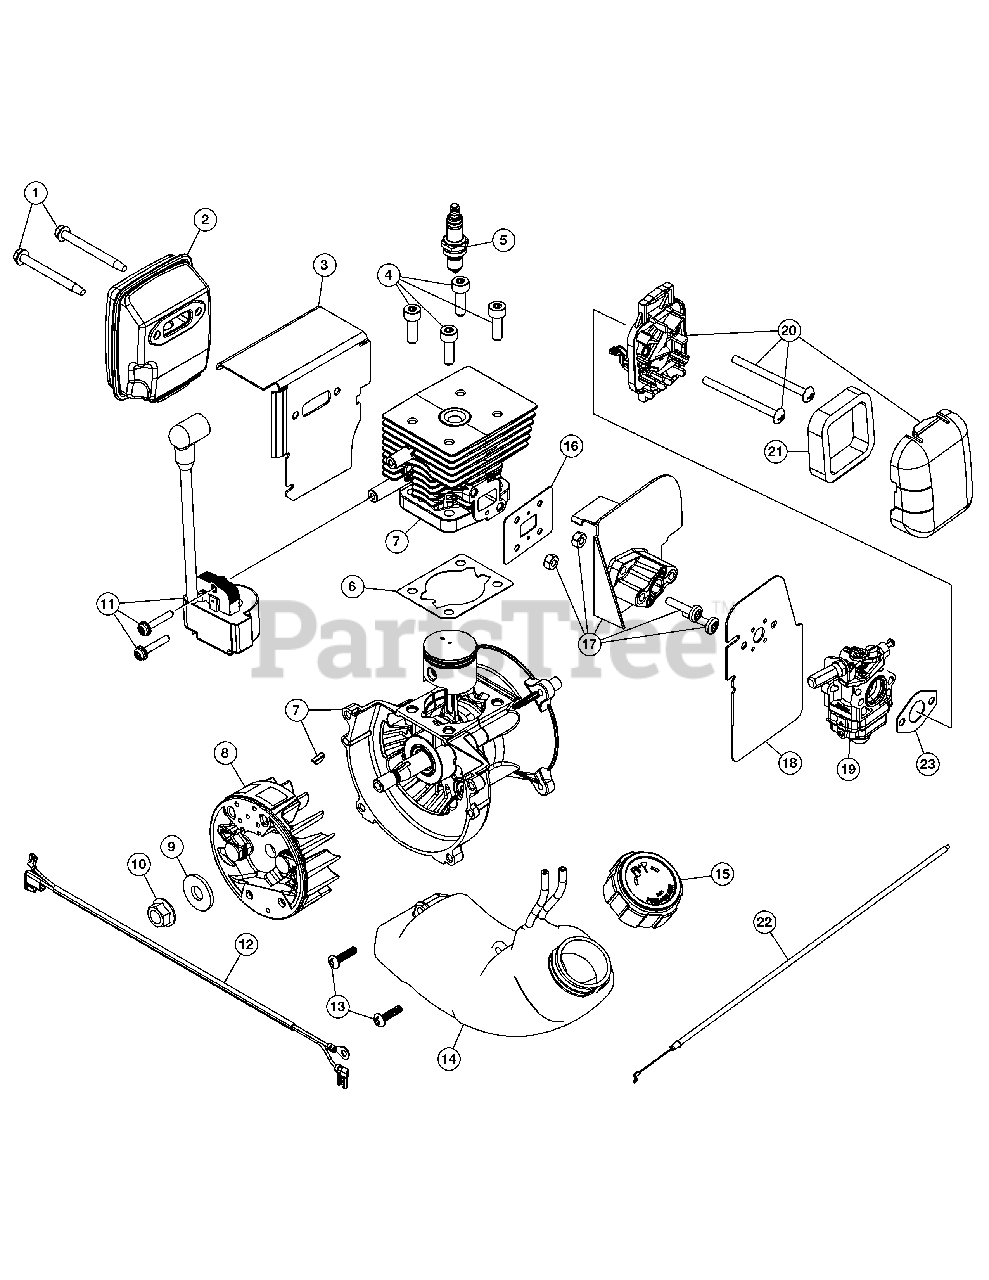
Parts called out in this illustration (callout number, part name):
1	Muffler Screw
2	Muffler Assembly (Incl. 1 & 3)
3	Muffler Gasket
5	Spark Plug
6	Cylinder Gasket
7	Shortblock Assembly (Incl. 4 - 6 & 8 - 11)
8	Flywheel Assembly
11	Module Assembly
14	Fuel Tank Assembly (Incl. 13 & 15)
16	Insulator Gasket
17	Insulator Assembly (Incl. 16)
18	Carburetor Gasket
19	Carburetor Assembly (Incl. 20)
20	Air Cleaner Assembly (Incl. 21)
22	Throttle Cable
23	Carburetor Gasket
